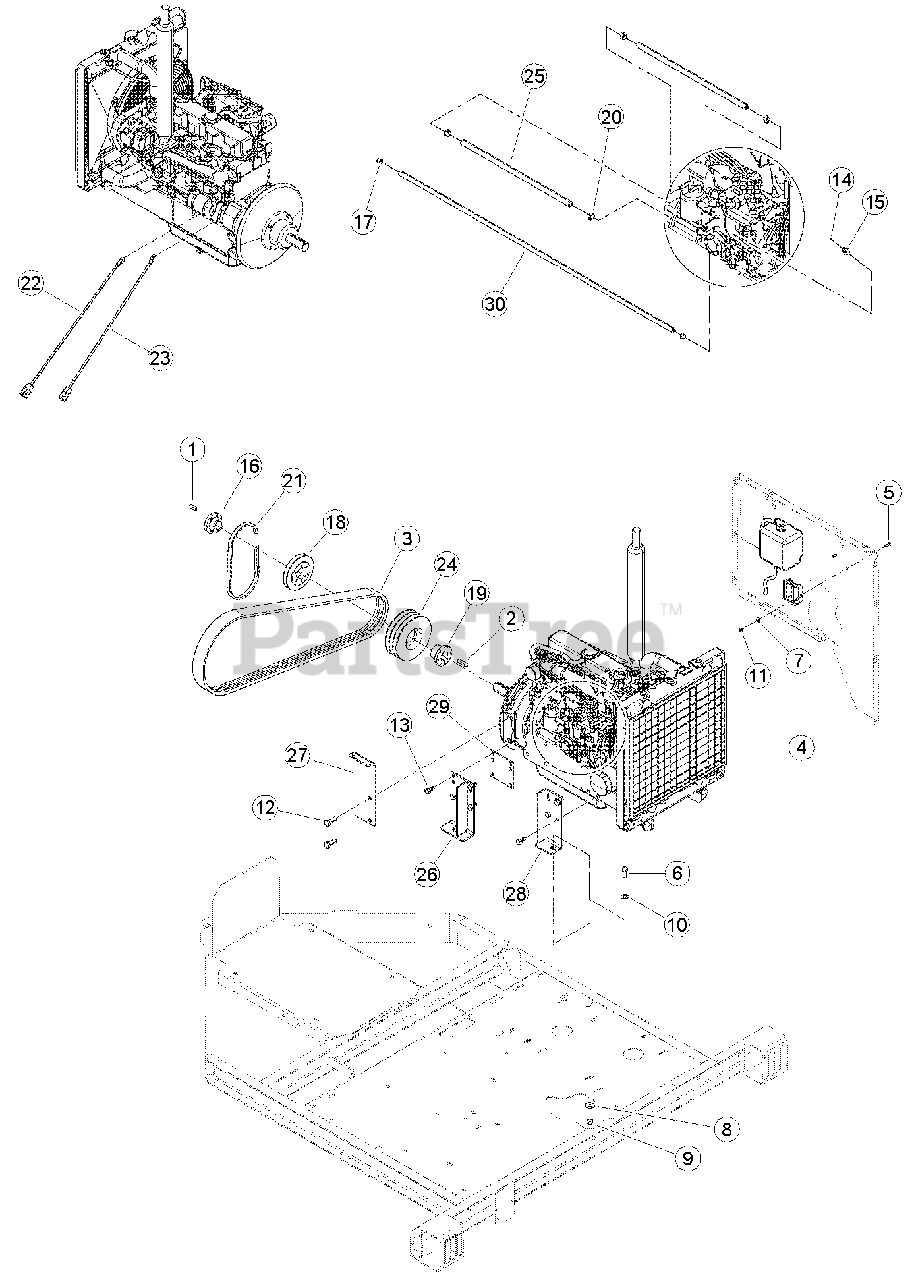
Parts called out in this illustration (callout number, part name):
1	KEY, 3/8 SQUARE X 1-1/4 LONG
2	KEY, 3/8 SQUARE X 1-3/4 LONG
3	BELT, 3B90 BANDED
4	ENGINE, 2203 KUBOTA DIESEL
5	BOLT, 1/4 X 3/4 HEX HD GR5 ZP
6	BOLT, 1/2 X 1-1/4 HEX HD GR5 ZP
7	WASHER, 1/4 FLAT ZP
8	WASHER, 1/2 FLAT ZP
9	NUT, 1/2 CENTERLOCK GRB ZP
10	WASHER, 1/2 SAE FLAT ZP
11	NUT, 1/4 NE NYLOCK ZP
12	BOLT, M14-1.5 X 20 HEX HD GR8.8 ZP
14	SCREW, #8-32 X 3/16 KNR CUP PT
15	PIN, 1/4 BOWDEN
16	BUSHING, SDS 1-7/16
17	CLAMP, 15/32 SPRING
18	SHEAVE, 1B5.2 SDS
19	BUSHING, SD 1-7/16
20	CLAMP, 9/16 SPRING
21	BELT, BX30
22	CABLE, 72 IN. POSITIVE BATTERY
23	CABLE, 72 IN. NEGATIVE BATTERY
24	SHEAVE, 3B6.8 SD
25	HOSE, 15 IN. FUEL LINE
26	WELDMENT, ENGINE MOUNT
27	ANGLE, SPRING ANCHOR
28	WELDMENT, FRONT ENGINE MOUNT
29	PLATE, MOUNT SPACER
30	HOSE, 38 IN. FUEL LINE
